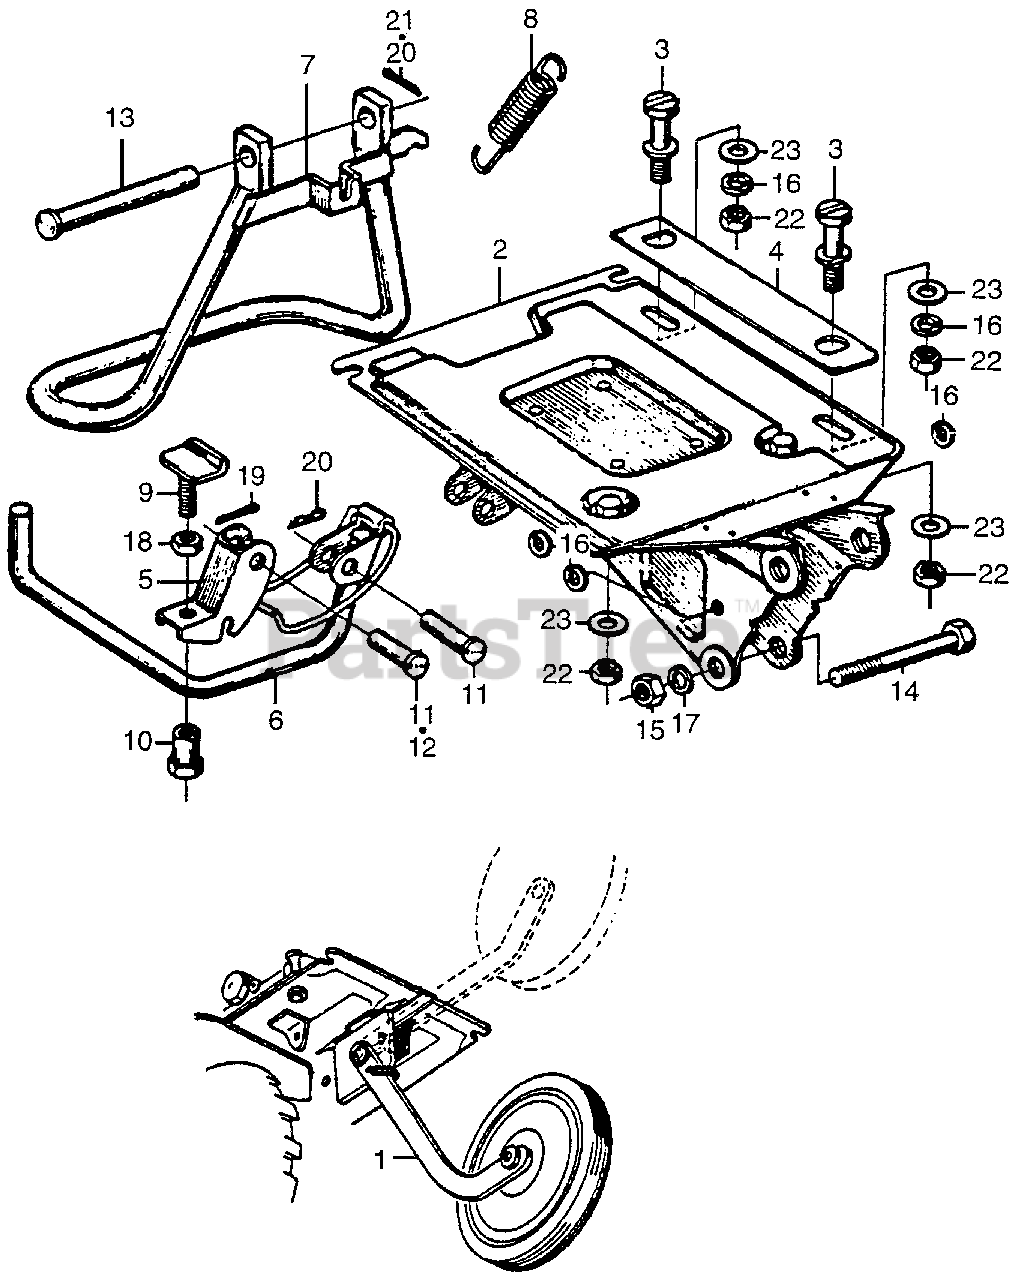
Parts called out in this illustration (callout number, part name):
2	FRAME, ENGINE
3	PIN, STOPPER (NOT AVAILABLE)
4	SPACER, ENGINE BED
5	ARM, ENGINE CLAMP
6	LEVER, SETTING
7	PIPE, STAND (NOT AVAILABLE)
8	SPRING, LOCK
9	BOLT, ADJUST (NOT AVAILABLE)
10	NUT, ADJUST (8MM) (NOT AVAILABLE)
11	PIN, ARM (NOT AVAILABLE)
12	PIN, STAND
13	PIN, SETTING LEVER
14	BOLT, HEX. (10X50)
15	NUT, HEX. (10MM)
16	WASHER, SPRING (8MM)
17	WASHER, SPRING (8MM)
18	NUT, HEX. (8MM)
19	PIN, COTTER (2.0X15)
20	PIN, COTTER (3.0X18)
21	PIN, LOCK (8MM)
22	NUT, HEX. (8MM)
23	WASHER, PLAIN (8MM)
